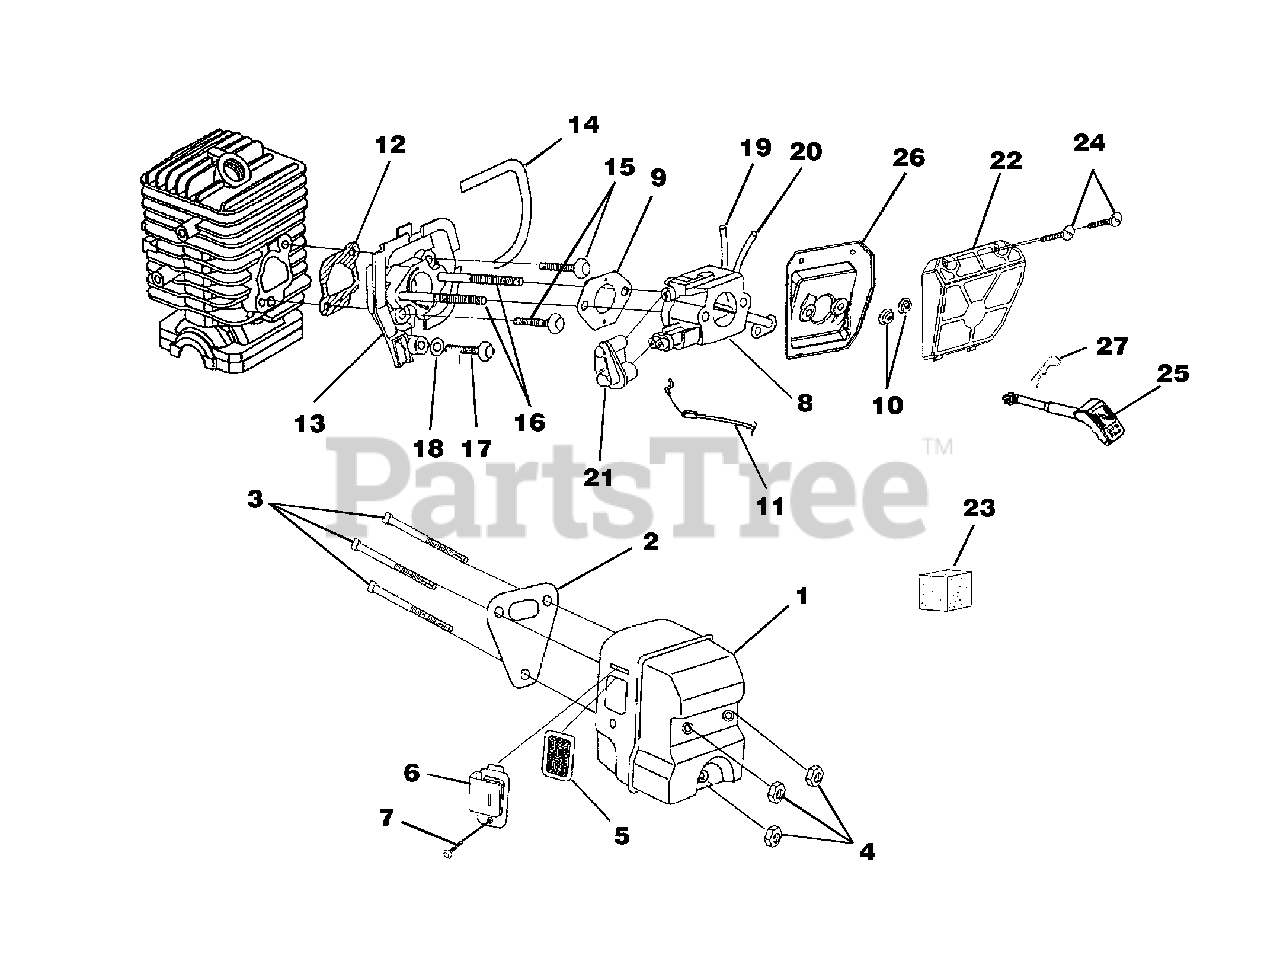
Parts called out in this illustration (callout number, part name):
1	Muffler Kit
2	Muffler Gasket
3	Screw-Square Hd.
4	Nut-Locking Hex (10-32)
5	Screen, Spark
6	Deflector, Muffler
7	Screw
8	Carburetor Assembly
9	Carburetor Gasket
10	Flange Nut (10-24)
11	Throttle Cable
12	Gasket, Heat Dam
13	Heat Dam
14	Seal, Heat Dam
15	Screw, Truss Hd. Taptite (10-24 x 7/8")
16	Screw, Carburetor
17	Screw, Thread Form (10-14 x 1/2")
18	Washer, Retaining
19	Fuel Line (Tank to Carburetor 8 1/2")
20	Fuel Line (Carburetor to Purge Bulb 4")
21	Carburetor Grommet
22	Air Filter Cover
23	Pre Filter (In engine housing)
24	Screw-Slotted Pan Hd. (8-16 x 5/8")
25	Rod, Choke
26	Air Filter Plate
27	Spring Clip (Choke Rod)
